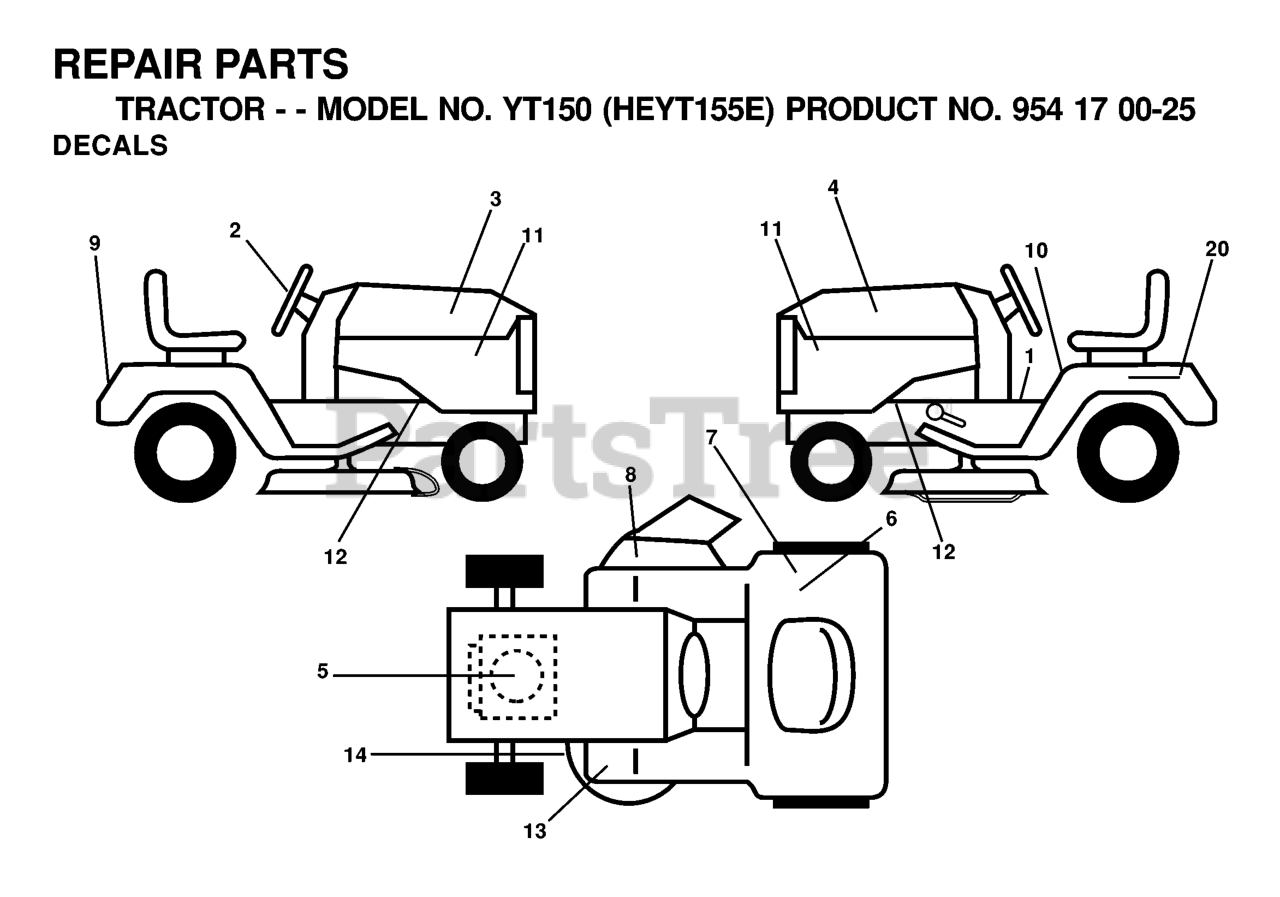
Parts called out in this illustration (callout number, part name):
1	DECAL PARK BRAKE
2	DECAL.WHEEL.STEERING.HUSQ.PERM
3	Decal Hood RH
4	Decal Hood LH
6	DECAL CERTIFICATION
7	DECAL EUROPE STANDARD CE
8	DECAL MOWER CUT/FINGER
9	DECAL FENDER HUSQ
10	DECAL READ OWNER'S MAN SYMS
11	DECAL PNL SIDE
13	DECAL
14	DECAL V BELT SCHEMATIC
20	DECAL BTRY SYMBOLS
